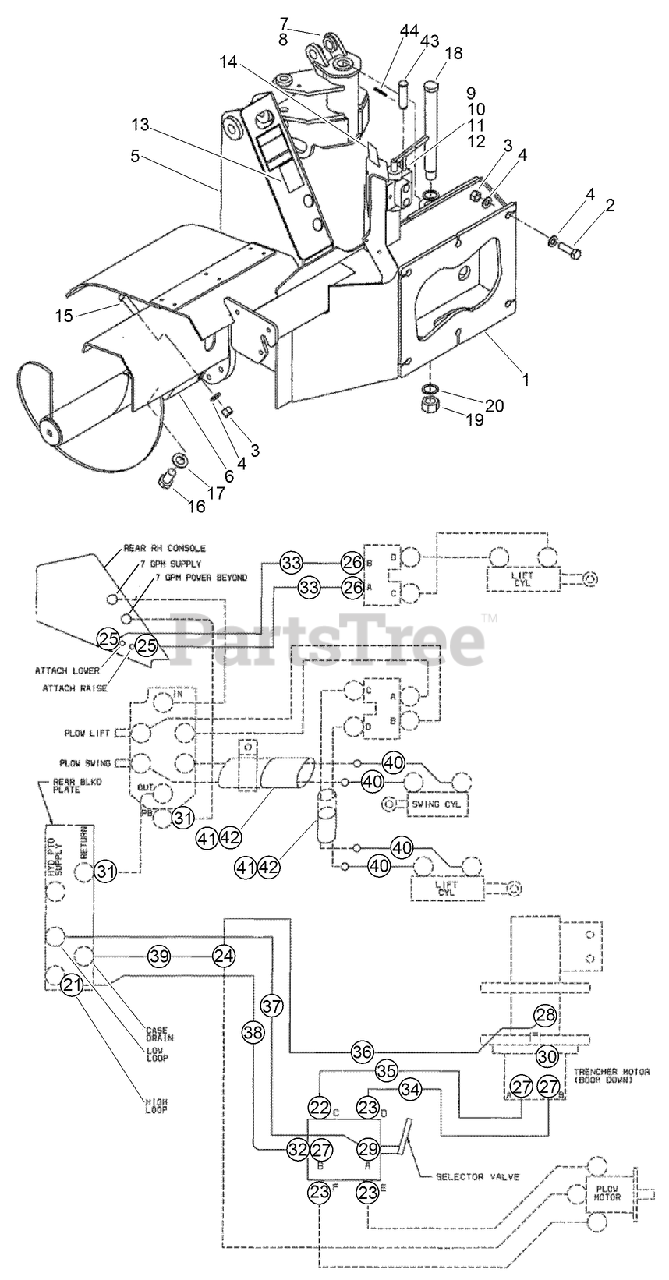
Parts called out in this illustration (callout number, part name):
1	FRAME-Quad
3	NUT-3/4 TL Grd C
4	WASHER-Flat
5	ASM-Trencher
6	DRIVE-Trencher
7	PLOW-Basic P75
8	PLUMBING-P75 Plow
9	VALVE-Selector, 6 Port
10	BOLT-hex, 3/8 NC x 3 inch
11	NUT-HEX
12	WASHER-FLAT
13	DECAL-Quad Selector
14	DECAL-plow control pattern, lift/swing
15	SCREW-HH
18	PIN-pivot, plow
20	WASHER-flat, 1-17/32 x 2-1/16 x 1/8 inch
21	REDUCER-16FF-12MF
22	ELBOW-90 Deg 12MO x 12MF
23	ELBOW-45 Deg 12MO x 12MF
24	TEE-10MJ x 10MJ x 10MJ
25	ELBOW-SWIVEL, 90 DEG
26	CONNECTOR
27	FITTING-STRAIGHT
28	ELBOW-90 Adj 37FL 5/8 Tube
29	ELBOW-90 Adj 37FL 3/4 Tube
30	PLUG-Hex Hd, ORB 3/8
31	ELBOW-45 Deg 12MJ x 12FJ
32	FITTING-ELBOW, 90
33	HOSE-Boom Lift
34	HOSE-Low Pressure Loop
35	HOSE-High Pressure Loop
36	HOSE-Case Drain
37	HOSE-Selector Valve Lo Loop
38	HOSE-Selector Valve Hi Loop
39	HOSE-Case Drain
40	HOSE-Extension
41	SLEEVE-Nylon
42	STRAP-TIE
43	PIN-clevis, 1 x 3-1/2 inch, hardened
44	PIN-cotter, 5/32 x 1-3/4 inch
